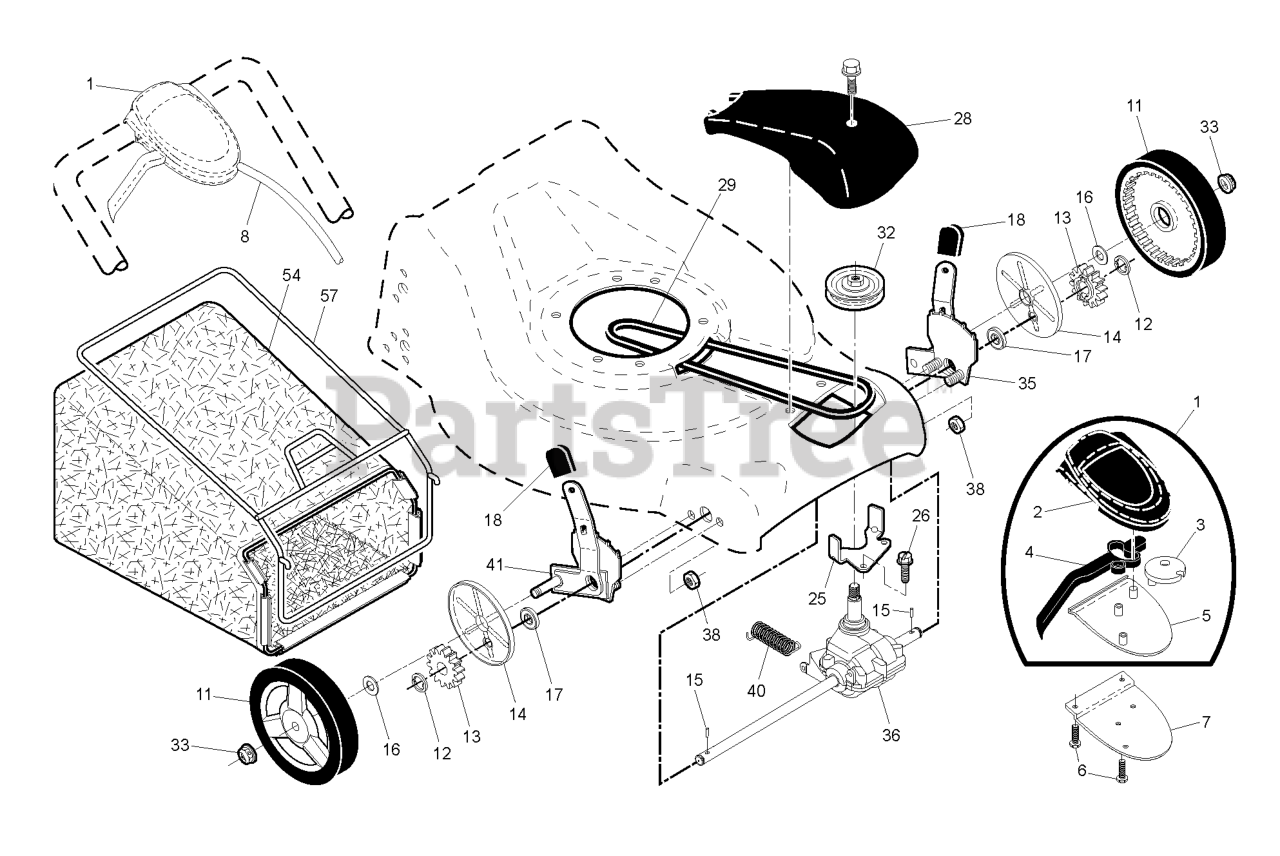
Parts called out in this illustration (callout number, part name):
1	CONTROL.DR.QW.21FGD.BS.GY/BLK
2	COVER TOP AUTO WALK CONTROL
3	PULLEY.CAM.DRIVE.CONTROL.EZ
4	LEVER.BLACK
5	COVER BOTTOM AUTO WLK CONTROL
6	SCREW, PHILLIPS HEAD 10 X 5/8
7	BRACKET.DRIVE.CONTROL.MOUNT.BL
8	CABLE ASSEMBLY, DRIVE
11	WHEEL.8X1.75.H3SPK.RAD3.GY.BU3
12	E-RING 7/16 RE
13	PINION.14.TEETH.FGD
14	COVER.DUST.WHEEL
15	PAWL, DRIVE
16	WASHER FLUT
17	BEARING
18	SELECTOR KNOB
25	BELT KEEPER
28	COVER.DRIVE.ASM.185579.CE.WALK
29	BELT.DRIVE.FG
32	RP PULLEY.DRIVE.EZ
33	NUT.HEX.FLANGE.3/8-16.LO(3 2)
35	RP KIT, WHEEL ADJUSTER, LH
36	TRANSMISSION.21.FGD.HT.VST
38	LOCKNUT.NYLOC.1/4-20
41	KIT, WHEEL ADJUSTER, RH
54	Grassbag Assembly
57	FRAME.GBAG.21.FWGD
